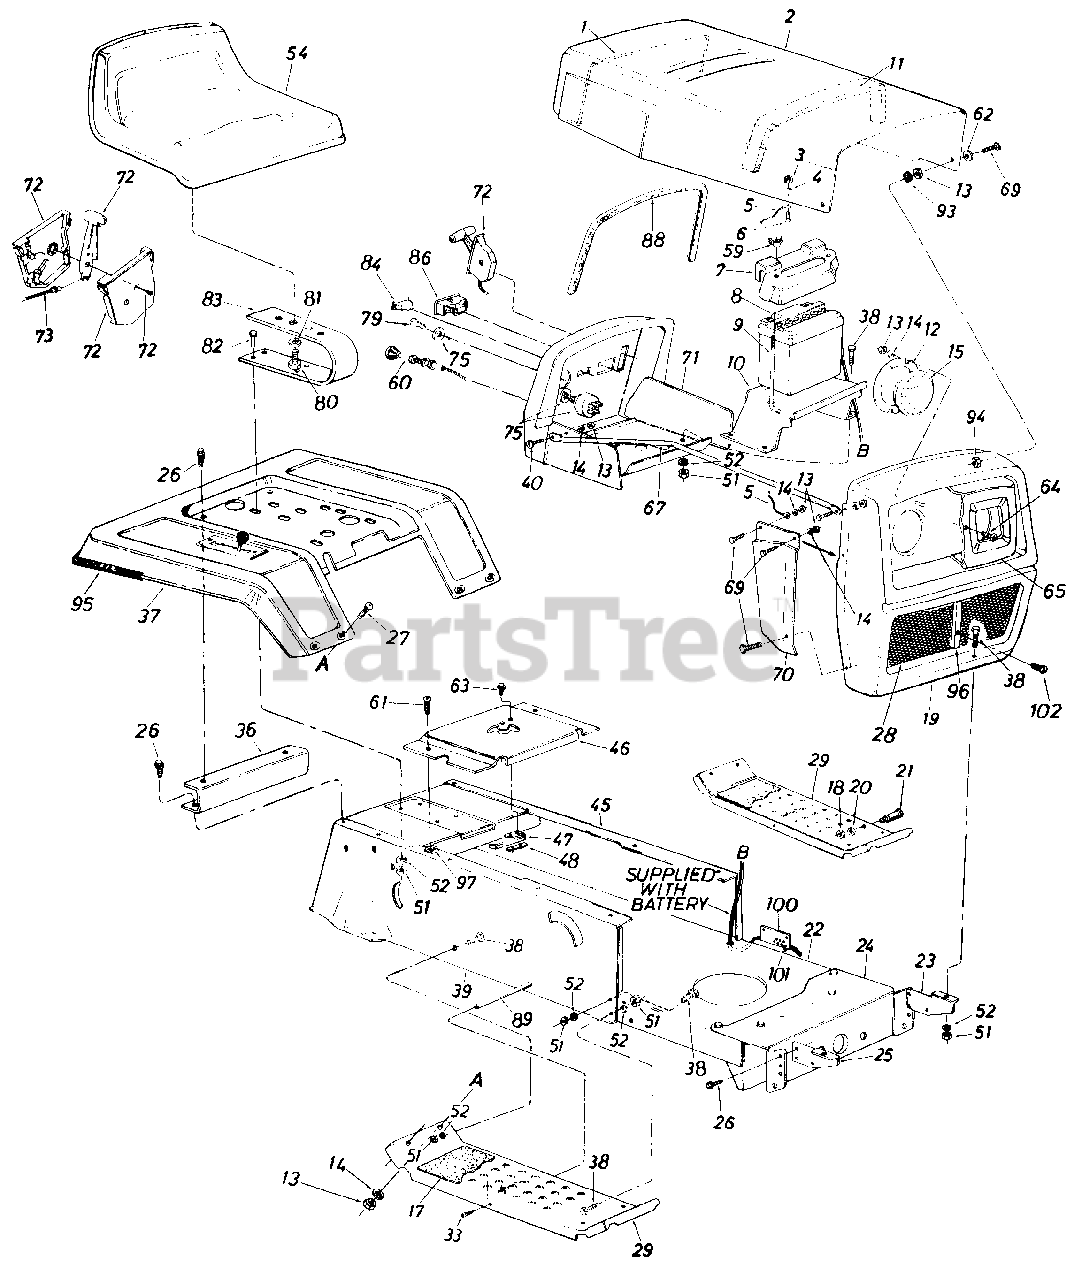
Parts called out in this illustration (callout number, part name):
1	Hood Spring
2	Hood
3	Hex Sems Nut #10-24 Thd.*
4	Fl-Wash. .281" I.D. x .62" O.D. x .051
5	Hood Stop 7" Lg.
6	Truss Hd. Scr. #10-24 x 1/2"*
7	Battery Cover
8	12 Volt Battery
9	Battery Hold Down Rod
10	Battery Bracket
11	PVC Foam Strip
12	Headlight Retainer
13	Hex Nut 1/4-20 Thd.*
14	L-Wash 14" I.D.*
15	Headlight
15	Hex Wash. Hd. Tap Scr. 1/4 x 3/8" Lg.
17	Foot Pad
18	Hex Nut 3/8-16 Thd.*
19	Grille Ass'y.
20	L-Wash. 3/8" I.D.*
21	Shld. Bolt .50" Dia. x .84
22	Lower Frame
23	Grille Mount Brkt. L.H.
24	Front Pivot Brkt.
25	Grille Mount Brkt. R.H.
26	Hex Wash. Hd. AB-Tap Scr. 5/16 x .75" Lg.
27	Carr. Bolt 1/4-20 x .50" Lg.*
28	Grille Screen
29	Running Board (R.H. & L.H.)
33	Truss Mach. Scr. 5/16-18 x .75" Lg.*
36	Fender Mount Brace
37	Fender
38	Hex Bolt 5/16-18 x .75" Lg.*
39	R.H. Side Frame
40	Hex Bolt 1/4-20 x .62" Lg.*
45	L.H. Side Frame
46	Shift Cover
47	Reverse Safety Switch
48	Insulator Nut Plate
48	Hitch Plate
51	Hex Nut 5/16-18 Thd.*
52	L-Wash. 5/16" I.D.*
54	Seat Ass'y
59	Wing Nut 1/4-20 Thd. Plastic
60	Choke Control
61	Truss Mach. Tap Scr. #10 x .50" Lg.
62	Fl-Wash. .296 I.D. x .62 O.D.
63	Truss Mach. Scr. 1/4-20 x .75" Lg.
64	Truss Hd. Scr. #10-24 x .38" Lg.
65	Bezel
69	Truss Hd. Scr. 1/4-20 x .75" Lg.*
70	R.H. Grille Side Panel
70	L.H. Grille Side Panel
71	Dash Panel Ass'y.
72	Throttle Control Box Ass'y.
73	Throttle Control Wire
75	Ignition Switch
79	Ignition Key
80	Hex Bolt 1/2-13 x 1.00" Lg.
81	L-Wash. 1/2" I.D.*
82	Hex Bolt 5/16-18 x 1.00" Lg.*
83	Seat Spring 5.5" High
84	Light Switch
86	Ammeter
88	Molding Strip 27" Lg.
89	Running Board Rod
89	Thread Rolling Scr. 1/4-20 x .50" Lg.
93	Rubber Wash. 1/2" I.D. x 1.0 O.D. x .25"
94	Hex Sems Ins. L-Nut 1/4-20 Thd.
95	Trim Strip 81"
96	Center Moulding
97	Speed Nut #10Z
100	Brake Cable Bracket
101	Cable Tie
102	Truss Mach. Scr. #10-24 x .62" Lg.
